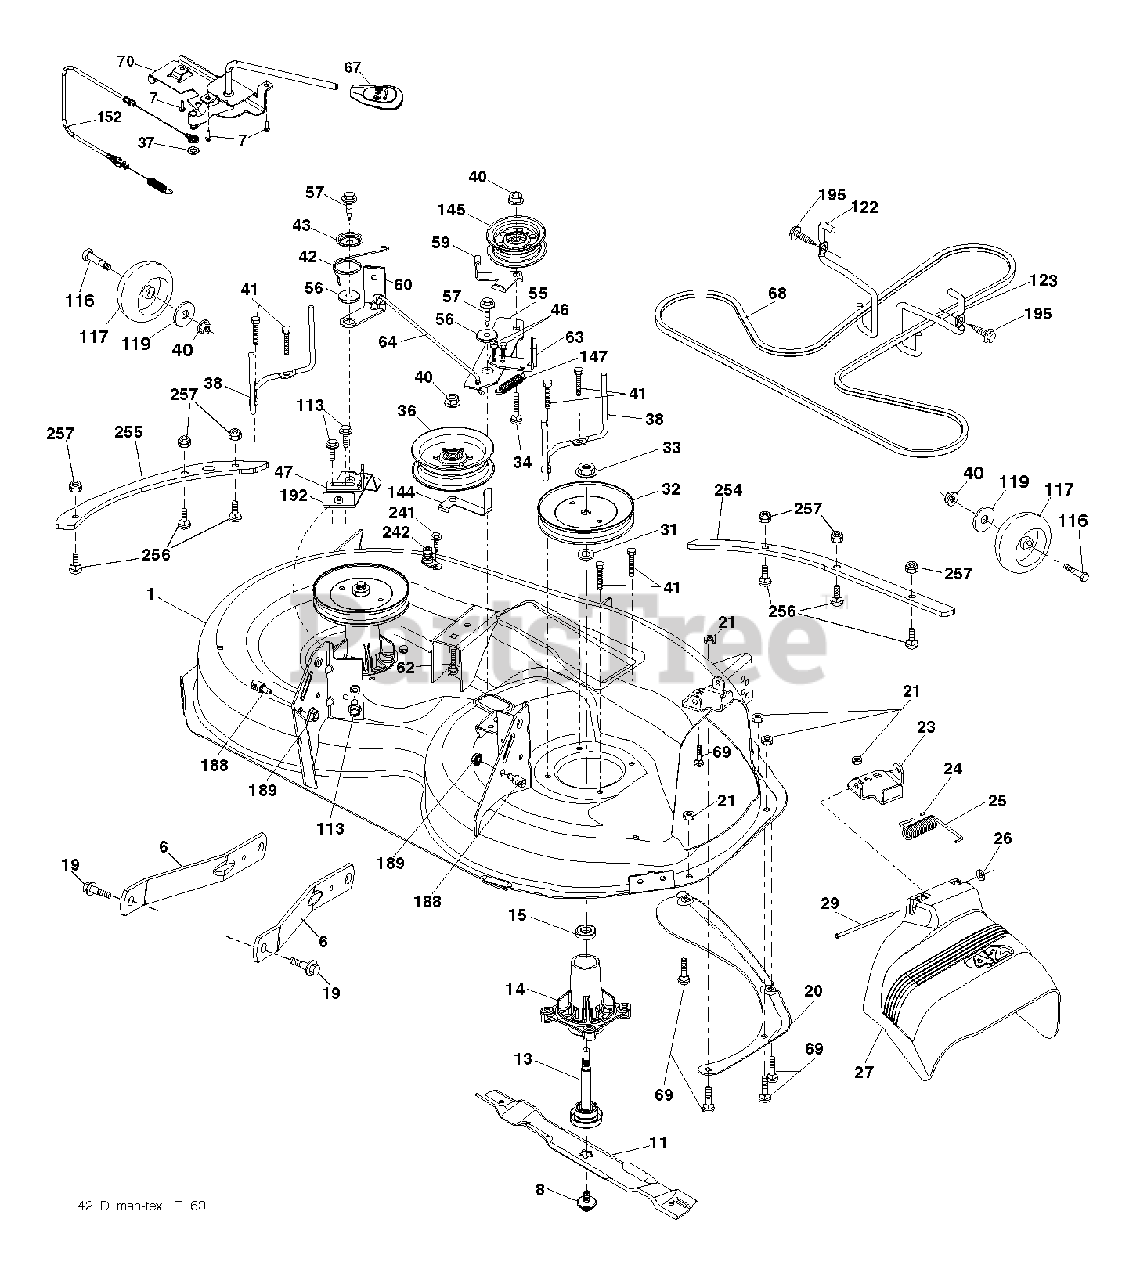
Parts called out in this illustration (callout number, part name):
1	DECK SVC 42" 2GWB 419175X668
6	ARM.SUSPENSION.MOWER.R
7	SCREW.#10 X 0.750.BOS
8	BOLT.WASHER.ASM.7/16-2
11	42" HI-LIFT BLADE
13	SHAFT.ASM.MDRL.N/GREASE.38
14	HOUSING.MANDREL.4PT.
19	BOLT.SHOULDER
20	BAFFLE.VORTEX
21	LOCKNUT
23	BRKT.DEFLECTOR.38"2005+
24	CAP-SLEEVE LT
25	SPRING.TORSION.DEFLECT
26	NUT PUSH M
27	SHIELD.DEFLECTOR.MOWER.42"BLAC
29	ROD.HINGE
31	WASHER.SPACER.MANDREL
32	PULLEY.MANDREL.5.438.PD
33	NUT.FLANGE.LOCK.TOP
34	BOLT.3/8-16X1.50
36	PULLEY.IDLER.2006
37	WASHER
38	KEEPER.BELT.MANDREL.PULLEY
40	NUT LOCK FLG 3/8-16 UNC
41	BOLT.HEX.WASHR.HED.313-18X1.19
42	SPRING.TORSION.BRAKE
43	SRPING.TORSION.RETAINE
46	SCREW.1/4-20X5/8
47	BRKT.CLUTCH.CABLE
55	IDLER.ARM.42"
56	SPACER.RETAINER
57	SCREW 3/8-16X1
59	GUARD, BELT
60	ARM BRAKE MOWER
63	ARM BRAKE MOWER
64	LINKAGE.BRAKE.ASM.ZINC
67	HANDLE.CLUTCH.CABLE.LT
68	BELT.DECK.DRIVE.42"
69	BOLT
70	CLUTCH.ASM.MANUAL.YT.PREDATORQ
113	BOLT.5/16HEX.WHS.HD
116	BOLT.SHOULDER.3/8-16X3-5/8.
117	WHEEL. GUAGE RALLY
119	WASHER
122	KEEPER BELT ENGINE LH
123	KEEPER BELT RH
144	KEEPER.BELT.MOWER
145	PULLEY.IDLER.48"PRIMARY
147	RETURN SPRING
152	CABLE.CLUTCH.CABLE.W/SPRING
188	STUD.FASTNER.W/ANTI-ROTATE
189	NUT LOCK HEX FLANGE 5/16-18
192	BRKT.BRAKE.STAND.LH.
195	SCREW, 3/8-16X3/4
241	SCREW.TT.#10-32X.5.3/8.FLANGE
242	PORT.WASHOUT
254	PLATES.RENFRC.42DECK.PT431FRNT
255	PLATES.RENFRCE.42DECK.X431SIDE
256	RHSNB, 1/4-20 X 1, GR5
257	NUT T
